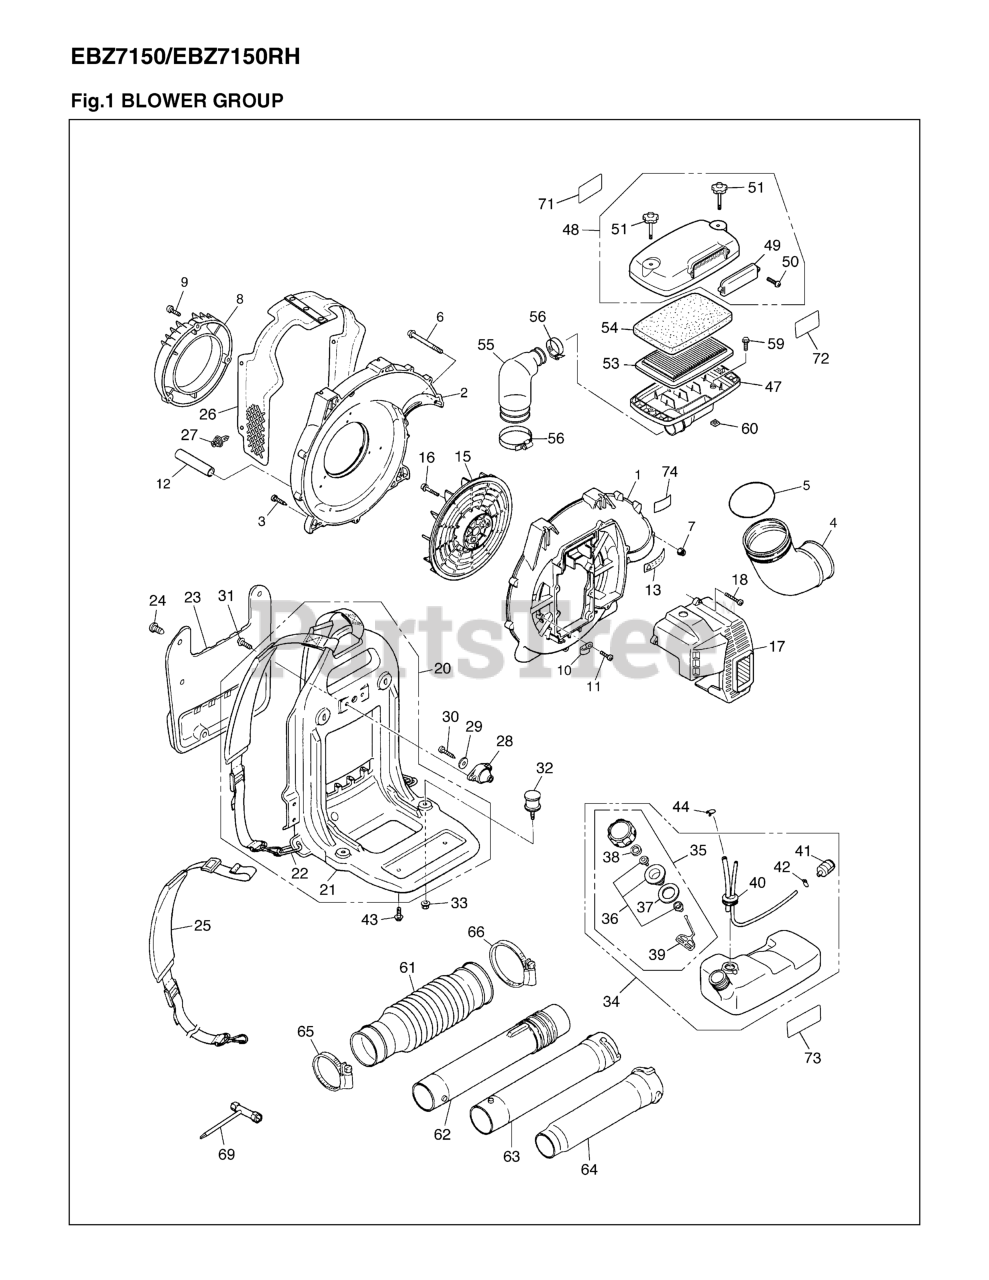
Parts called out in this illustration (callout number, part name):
1	VOLUTE CASE
2	VOLUTE COVER RPLS 848L5C55B3
3	SCREW
4	ELBOW
5	O-RING
6	SCREW TORX
7	NUT (B)
8	COVER, INLET
9	SCREW
10	CLAMP
12	TUBE (RPLS. 07270-01507)
13	LABEL CE CAUTION
15	FAN
16	BOLT
17	ENGINE COVER
18	SCREW
20	FRAME ASSY
21	FRAME COMP
22	RING (REPLACES -21120)
23	PAD
24	CLIP (RPLS 3490-21320)
25	BAND ASSY
26	NET COMP
27	CLIP
28	DAMPER, UPPER
29	WASHER
30	BOLT, TORX
31	SCREW TORX
32	DAMPER, LOWER
33	NUT, M6
34	TANK ASSY
35	CAP ASSY
36	HOLDER (REPLACES -85230)
37	PACKING
38	FILTER
40	PIPE COMPLETE
41	FILTER ASSY
42	CLIP (REPLACES 2841-31280)
43	SCREW TORX
44	CLIP
47	BODY, CLEANER
48	COVER ASSY
49	COVER
50	SCREW
51	KNOB BOLT (RPLS T4012-82800)
53	ELEMENT PAPER (RPLS T401282310)
54	ELEMENT (FOAM) (RPLS -82320)
55	HOSE
60	NUT
61	HOSE
62	SWIVEL JOINT
63	PIPE, STRAIGHT
64	PIPE, END
71	LABEL
74	LABEL, SOUND
